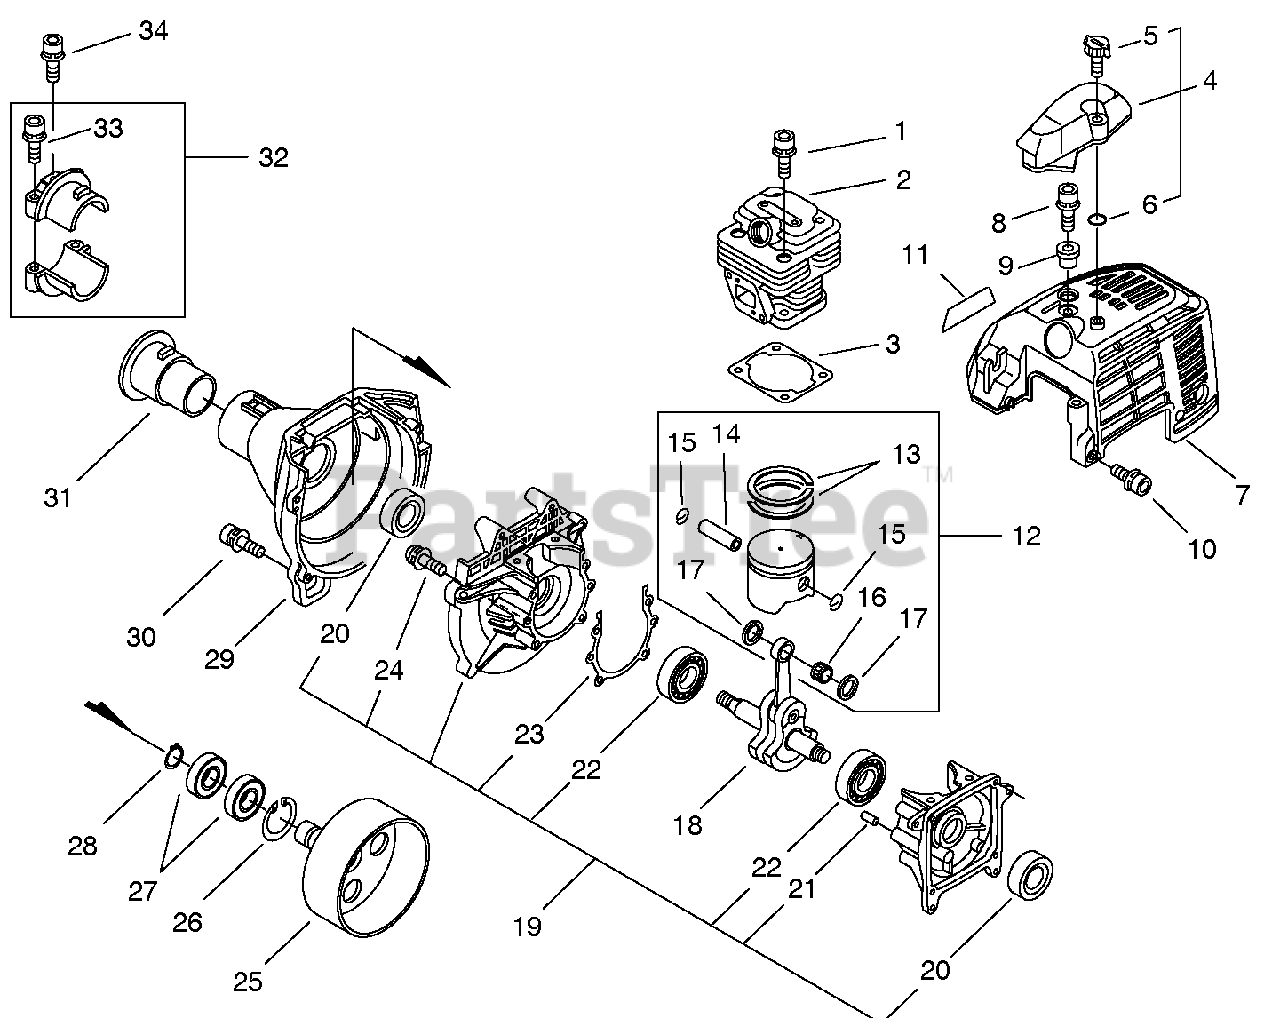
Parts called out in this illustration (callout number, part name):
1	SCREW - 5X20
2	CYLINDER
3	GASKET, CYLINDER
4	GUARD KIT
5	KNOB, FASTENER
6	O-RING - 4
7	COVER, ENGINE
8	SCREW - 5X20
10	SCREW - 5X12
11	LABEL - MODEL SRM-3605
12	PISTON KIT
13	RING, PISTON
14	PIN, PISTON
15	RING, RETAINING
16	BEARING, NEEDLE
17	SPACER, PISTON
18	CRANKSHAFT ASSY
19	CRANKCASE KIT
20	SEAL, OIL
21	PIN - LOCATING
22	BEARING, BALL - 6201
23	GASKET, CRANKCASE
24	SCREW - 5X30
25	DRUM, CLUTCH
26	RING, RETAINING - 28
27	BEARING, BALL - 6001
28	RING, RETAINING - 12
29	CASE, FAN
30	SCREW - 5X20
32	HOLDER KIT
33	SCREW - 5X25
34	SCREW - 5X12
